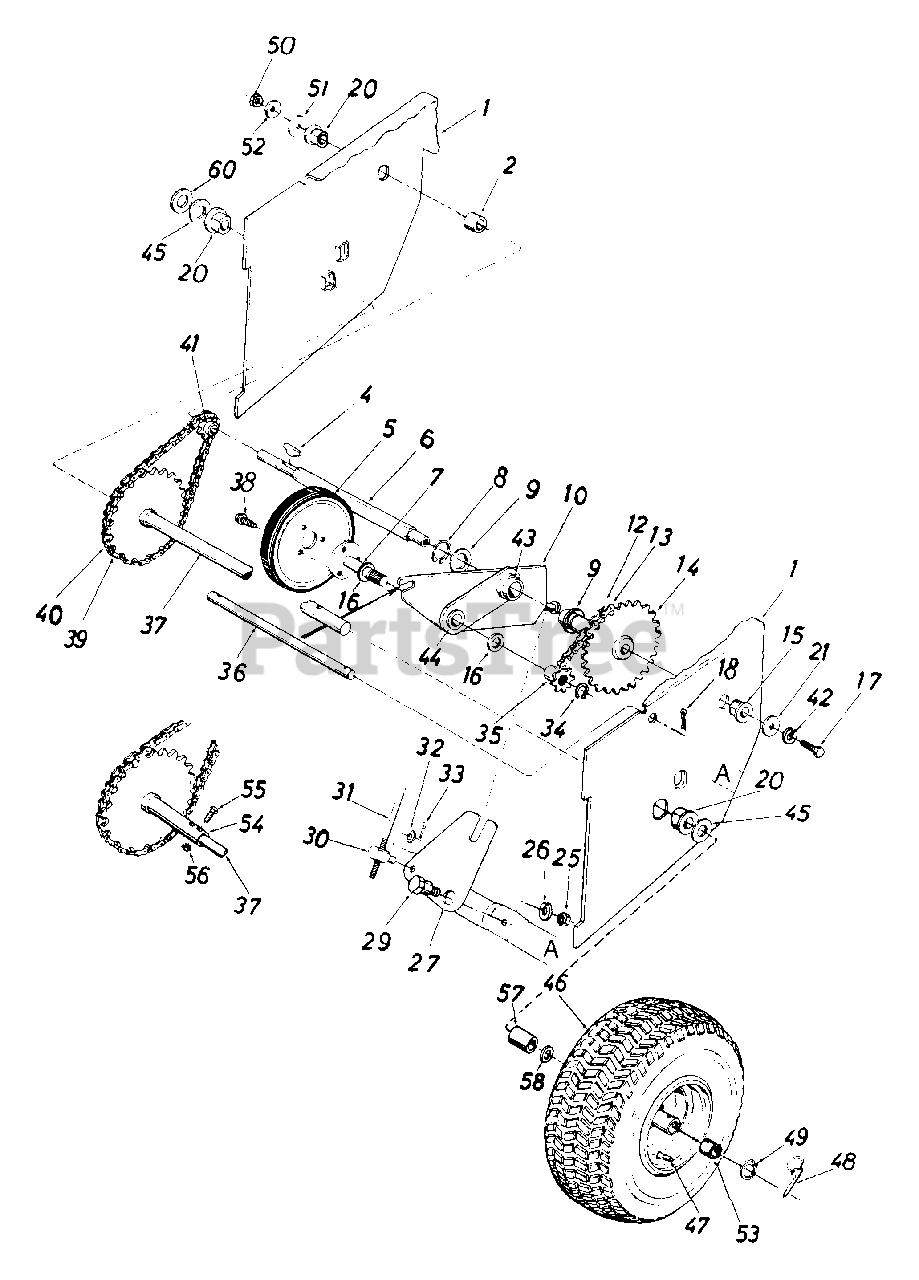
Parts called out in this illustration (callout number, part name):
1	Frame Ass'y.
2	Spacer .50" I.D. x .75" O.D. x .78" Lg.
4	#4 Hi-Pro Key 3/32 x 5/8" Dia.
5	Friction Wheel Ass'y.
6	Hex Shaft
7	Friction Wheel Mounting Plate Ass'y.
8	Snap Ring 1.00" Dia. Shaft
9	Fl-Wash. 1.00" x 1.63" O.D. x .03
10	Sliding Bracket Ass'y.
12	#41 Chain 1/2" Pitch x 35 Links
13	Master Link for #41 Chain
14	32 Teeth Sprocket Ass'y.
15	Hex Flange Brg. .630" I.D.
16	Fl-Wash. .62" I.D. x 1.00" O.D. x .06
17	Hex Lock Bolt 5/16-18 x .62" Lg.
18	Cotter Pin 3/32" Dia. x .75" Lg.
20	Flange Brg. w/Flats .75" I.D.
21	Fl-Wash. .34" I.D. x 1.12" O.D. x .125
25	Hex Jam Nut 3/8-16 Thd.
26	L-Wash. 3/8" I.D.
27	Shifting Linkage Bracket
29	Shld. Bolt .625" Dia. x .170" Lg.
30	Adjustment Ferrule
31	Shifting Rod 5/16" Dia. x 32.50" Lg.
32	Fl-Wash. .34" I.D. x .64" O.D. x .06
33	Cotter Pin 3/32" Dia. x .75" Lg.
34	Snap Ring .562" Dia. Shaft
35	Sprocket 7 Teeth x .50" Pitch
36	Shaft .50" Dia. x 9.50" Lg.
37	32 Teeth Wheel Axle Ass'y.
38	Hex Wash. Hd. Self-Tap Scr. 5/6-24 x .50" Lg.
39	#41 Chain 1/2" Pitch x 43 Links
40	Master Link for #41 Chain
41	8 Teeth Center Sprocket
42	L-Wash. 5/16" I.D.
43	Bearing
44	Bronze Bearing
45	Fl-Wash. .76" I.D. x 1.49 O.D.
46	Wheel Ass'y. Comp. 13 x 5.0
47	Air Valve
48	Klick Pin
49	Snap Ring .75 Dia.
50	Hex Ins. L-Nut 1/2-20 Thd.
51	Fl-Wash. .53 I.D. x 1.25 O.D. x .10
52	Bell-Wash. .50 I.D. x 1.0 O.D. x .075
53	Sleeve Brg.
54	32 Teeth Sprocket Hub Ass'y.
55	Hex Bolt 1/4-28 x 1.5"
56	Hex L-Nut 1/4-28 Thd. (586)
57	Spacer
58	Fl-Washer
60	Fl-Washer
